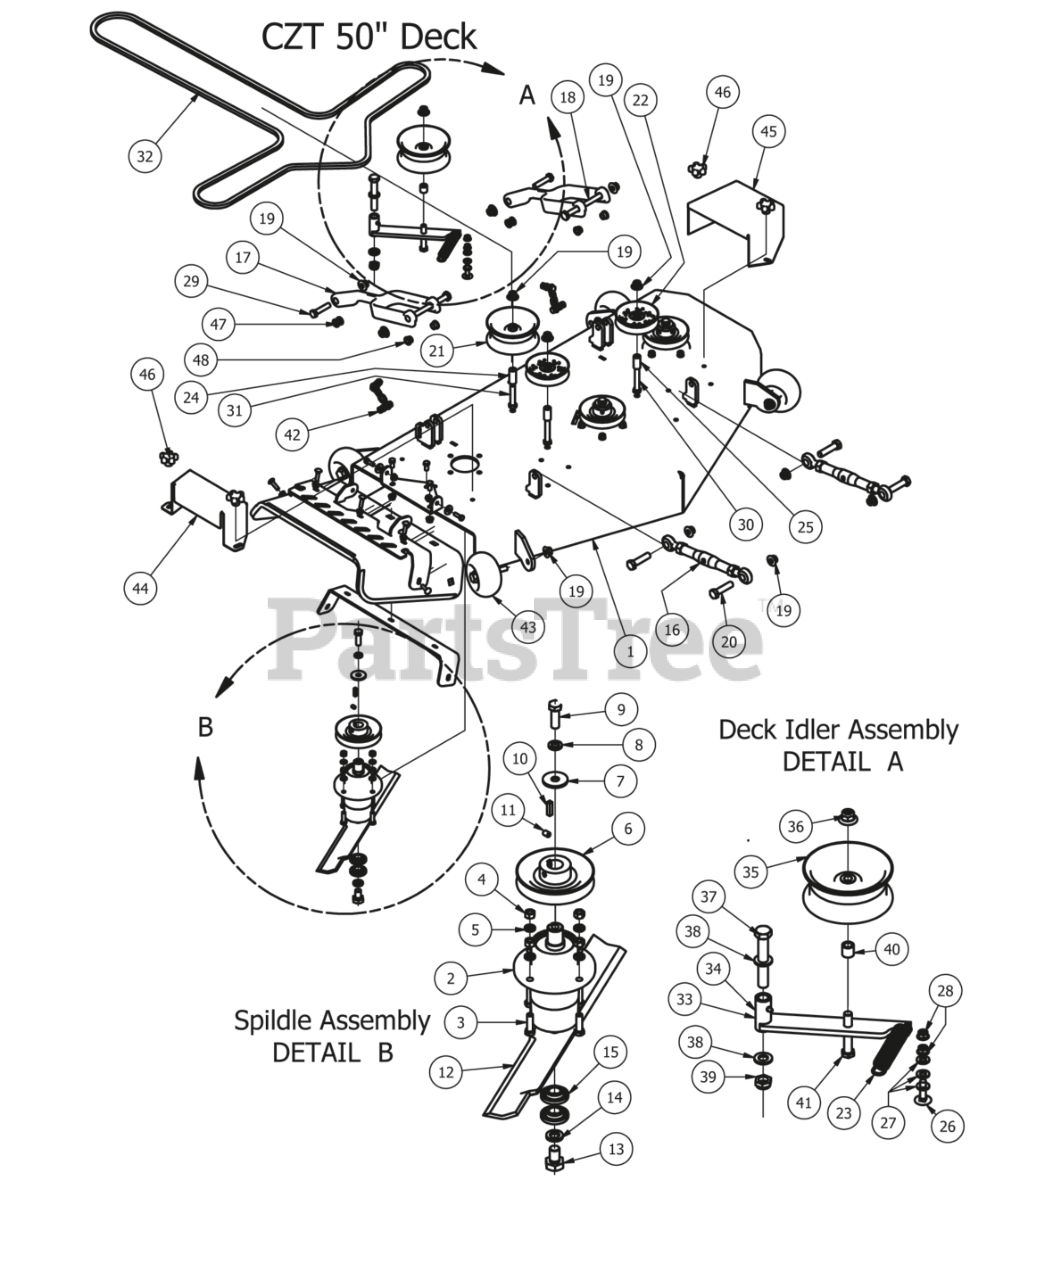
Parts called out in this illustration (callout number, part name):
2	Spindle- Aluminum - 2012
3	3/8" x 1 1/4" Hex Bolt
4	3/8" Hex Nut
5	3/8" Lock Washer
6	5" Deck Pulley
7	1/2 Belleville Washer
8	1/2" Lock Washer
9	1/2"-20 x 1 1/2 - Grade 5 Fine Thread Bolt
10	1/4" x 1" Key
11	3/8" Set Screw
12	50 Inch Fusion Blade
13	5/8" x 1 1/2" Grade 8 Bolt
14	5/8" Lock Washer
15	Spindle Bearing
16	Turnbuckle (Top Link
17	Deck Arm Assembly
18	1/2" x 5 1/2" Bolt
19	1/2-13 Nylon Flange Nut-Orange
20	5/8" x 2 1/2" Hex Bolt
21	5 3/4" Deck Idler Pulley
22	4-3/4 Idler Pulley
23	Deck Idler Spring
24	1 3/4" Pulley Spacer
25	Pup Pulley Spacer
26	3/8 x 1-1/2 Carriage Bolt
27	3/8" Flat Washer
28	3/8" Nylock Flange Nut
29	1/2-13X 2-1/4 GR Hex Bolts
30	1/2 x 3 1/2 Flange Bolt Grade 8
31	1/2" x 4" Bolt (Grade 8)
32	50" Deck Belt
33	Deck Idler Assembly Components 34,35,36,40,41
34	Deck Idler Bracket
35	5 3/4" Deck Idler Pulley
36	1/2-13 Nylon Flange Nut-Orange
37	5/8" x 4" Hex Bolt
38	.635 ID Plastic Washer
39	5/8" Nylock (1/2 Jam)
40	3/4 OD x 1/2 ID x 3\4 Length
41	1/2-13 x GR 5 Hex Bolt Zinc
42	Chain assembly
43	Deck Wheel
44	1/2 Metal Spindle Cover
45	Pulley Cover
46	5/16" Knob
47	Flange for Lower Deck Arm
48	Flange Bushing For Deck Arm upper
